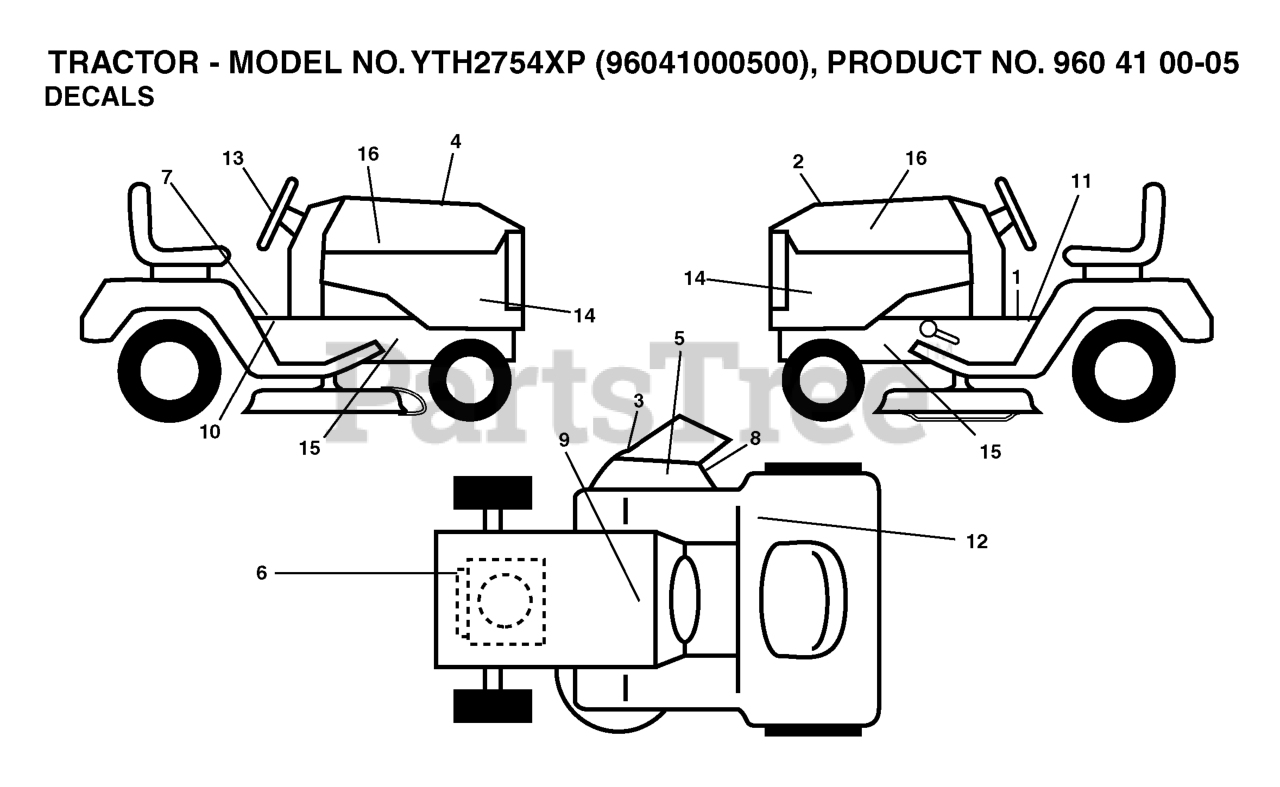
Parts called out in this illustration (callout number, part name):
1	DECAL
2	DECAL.HOOD.TOP.INSERT.
3	DECAL, DEFLECT WARNING
4	DECAL HOOD CUST. RESP.
5	DECAL.INTERNATIONL.CUTFINGER
6	DECAL
7	DECAL PARK BRAKE
8	DECAL.MOWER.SCH.48/54
9	DECAL BTRY SYMBOLS
10	DECAL
11	LABEL
12	DECAL
13	DECAL.STEERING.HUSQ.BLUE
16	DECAL.HOOD.NAMELOGO.HUSQ
